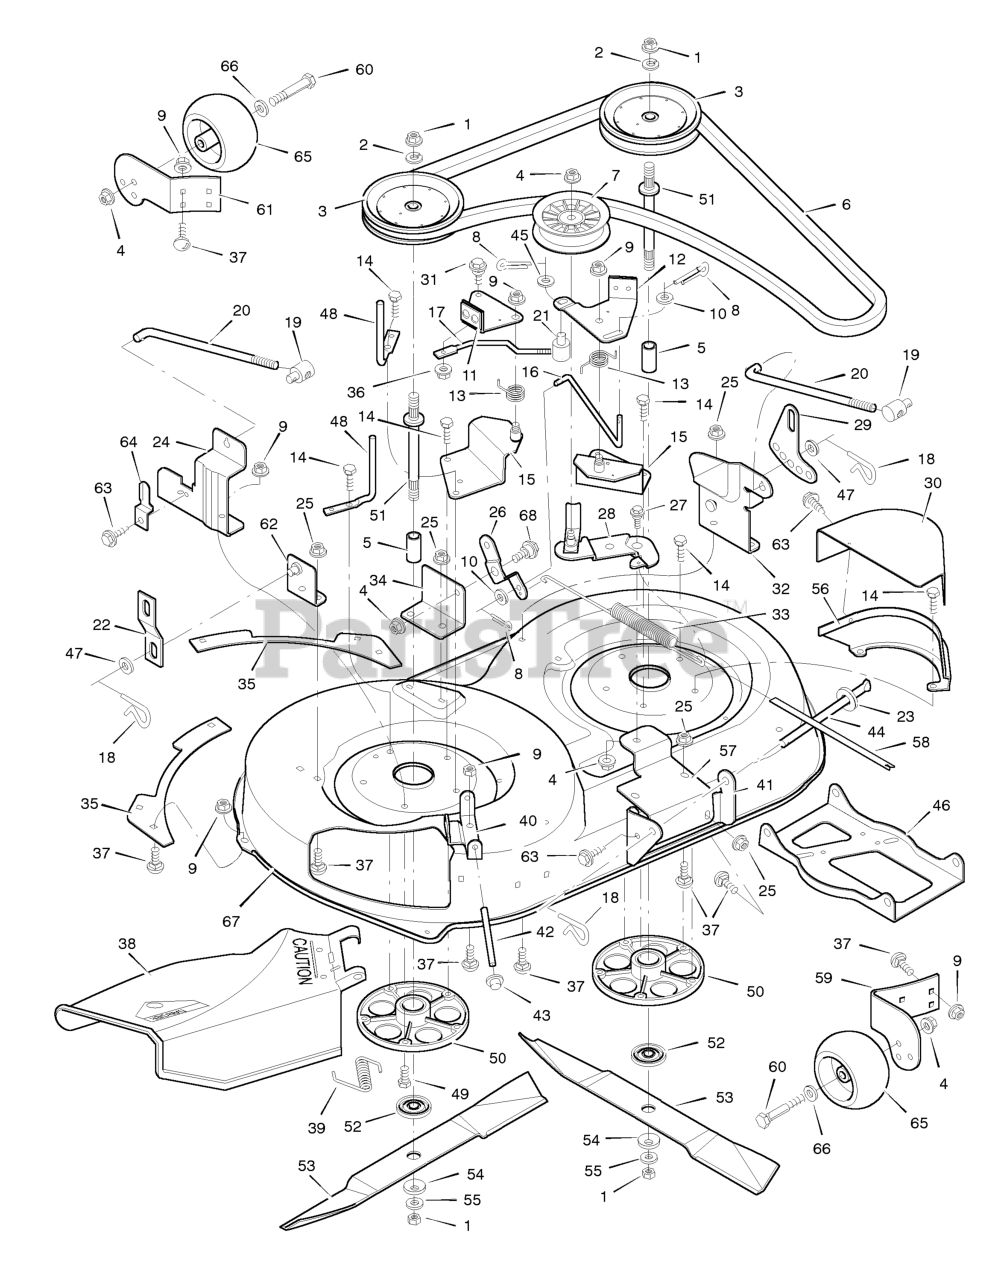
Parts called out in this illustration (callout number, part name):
1	Nut, Hex
2	Lockwasher
3	Pulley, Jackshaft
4	Locknut, Flange
6	Belt, Blade Drive
7	Pulley, Idler
8	Pin, Cotter
9	Locknut, Flange
11	Brake Assembly, Right
12	Brake Assembly, Left
13	Spring, Torsion
14	Bolt, Hex
15	Bracket Assembly, Brake
16	Rod, Brake
17	Rod, Cross Link
18	Pin, Hair
19	NUT, Adjusting, 1/2-13
20	Rod, Adjuster
21	Nut, Adjustable
24	Bracket, Right
25	Nut, Flange
26	Bracket, Pivot
27	Bolt, Shoulder
28	Arm Assembly, Idler
29	Plate, Adjuster
30	Cover, Pulley
31	Bolt, Shoulder
32	Bracket Assembly, Left Lifter
33	Spring, Extension
34	Bracket, Pivot
36	Locknut, Flange
37	Bolt, Carriage
38	Deflector Assembly, Chute
39	Spring, Torsion
40	Bracket, Hinge
41	Bracket, Front Hanger
42	Rod, Deflector
43	Cap, Push On
44	Rod, Hanger
46	Hanger, Front
48	Rod, Belt Guide
49	Bolt, Hex
50	Housing, Jackshaft
51	Jackshaft
52	Adapter, Blade
53	Blade, 42" (2 required)
54	Washer, Belleville
56	Bracket, Pulley Cover
57	Bracket, Idler Mount
58	Indicator, Plastic
59	Bracket, Right Wheel
60	BOLT, Gauge Wheel
61	Bracket, Left Wheel
62	Bracket Assembly, Right Lifter
64	Guide, Belt
65	Wheel, Gauge
66	Washer
67	Housing, Blade
68	Bolt, Shoulder
